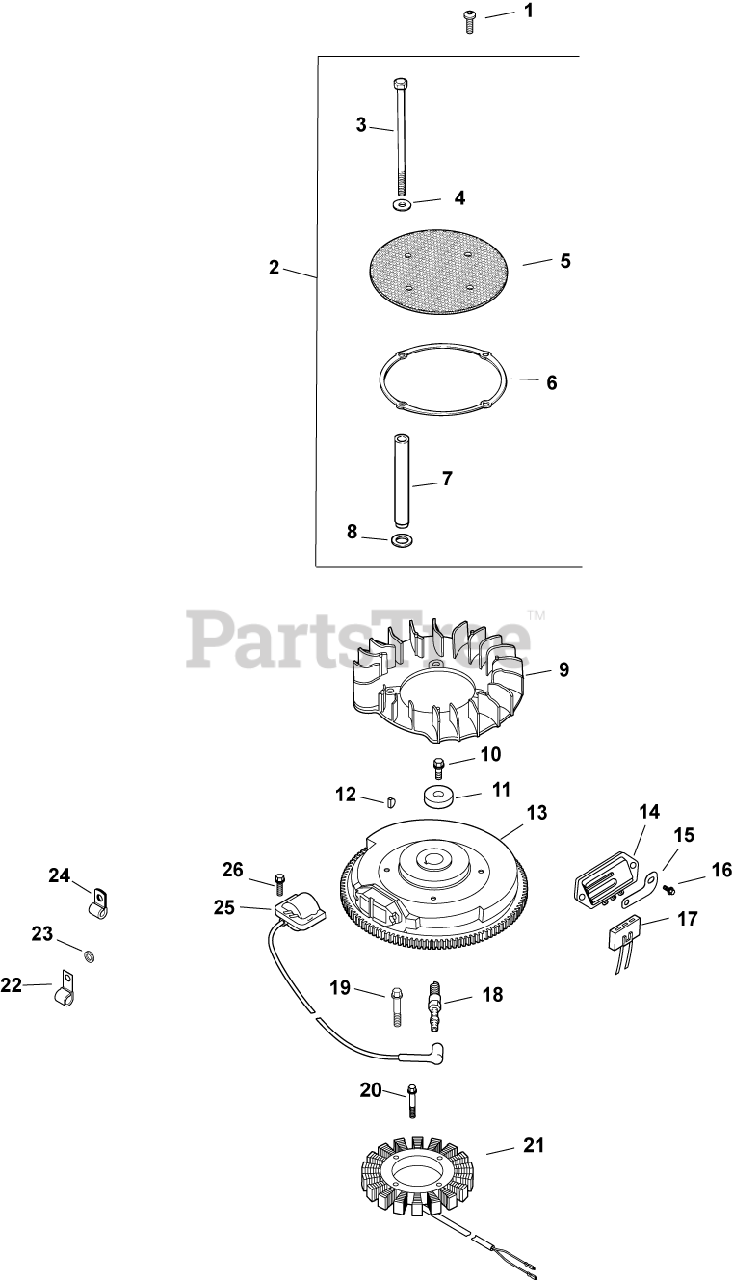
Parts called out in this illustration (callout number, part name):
1	SCREW, SOCKET TRUSS HD CAP
2	KIT, CHOPPER SCREEN
3	SCREW, CAP M6X1.0X99.5
4	WASHER, FLAT 1/4" (O.D. 5/8")
5	SCREEN, GRASS
6	RING, SUPPORT USE 25 141 08-S
8	WASHER, SPRING 10 MM
10	SCREW, FLG M10X1.5X45 - (#25086361S)
11	WASHER, FLAT 13/32"
12	KEY, 3/16" X 5/8"
13	FLYWHEEL ASSEMBLY (LW)
14	REGULATOR/RECTIFIER
16	SCREW, HEX FLANGE HI-LO
17	CONNECTOR
18	PLUG, SPARK (PRO SERIES)
19	SCREW, M5X0.8X25 - (#25086402S)
20	SCREW, SKT SET #10-24X1/4"
21	KIT, 15 / 20 AMP STATOR
22	CLIP, CABLE
23	WASHER, FLAT 1/4" (O.D. 1/2")
25	MODULE, SPARK ADV (DSAI)-USE 24 584 89-S
26	SCREW, FLG THD FRM M5X.8X20-(#25086399S)
